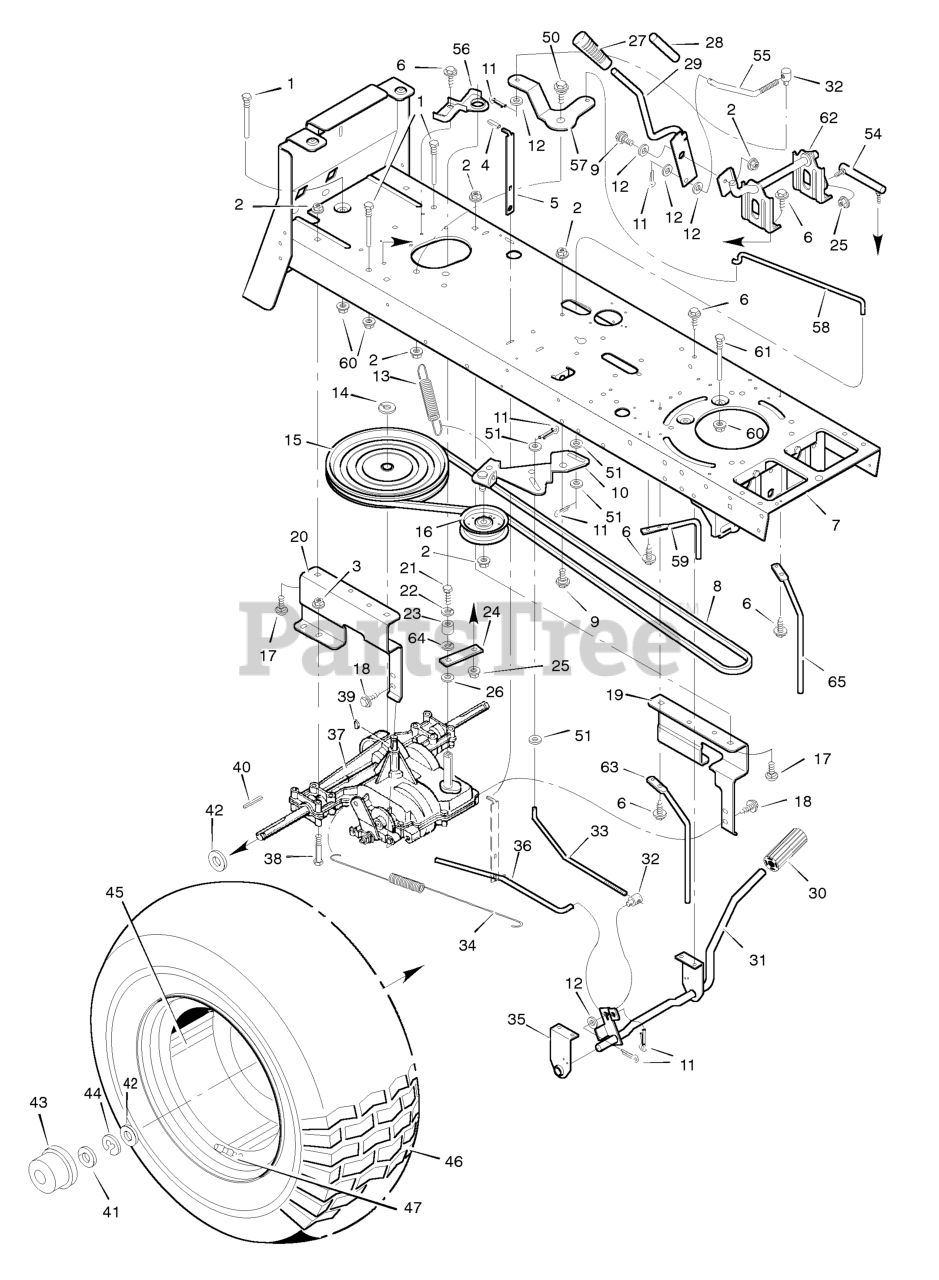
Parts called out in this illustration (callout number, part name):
1	Guide, Belt
2	Locknut, Flange
3	Locknut, Flange
5	Lever, Parking Brake
8	Belt, Motion Drive
9	Bolt, Shoulder
10	Bracket Assembly, Idler
11	Pin, Cotter
12	Washer
13	Spring, Drive Extension
14	Ring, Retainer
15	Pulley, Motion Drive
16	Pulley, Backside Idler
17	Bolt, Carriage
19	Bracket, Left Transaxle
20	Bracket, Right Transaxle
21	Bolt, Hex
22	Lockwasher
23	Pilot, Support
24	Yoke, Shift Lever
25	Locknut
28	Grip, Inner
29	Lever, Shift
30	Pedal, Clutch/Brake
31	Lever Assembly, Pedal
32	Nut, Adjustable
33	Rod, Clutch
34	Spring, Brake Extension
35	Bracket, Pedal Support
36	Rod, Brake Latch
37	Transaxle, Peerless **
38	Bolt, Hex
39	Key, Woodruff No. 9
40	Key, Square
42	WASHER, 1-1.3 16G FLT
43	Hub Cap
44	E- Ring
45	Wheel & Tire Assembly
46	Tire Only *
47	Valve Stem
50	Bolt, Shoulder
51	Washer
52	Washer
54	Link, Shifter
55	Link, Clutch
56	Bracket, Support
57	Bracket, Pivot
58	Rod, Clutch
59	Guide, Belt
60	Nut, Flange
61	Guide, Belt
62	Shifter Assembly
63	Guide, Belt
65	Guide, Belt
